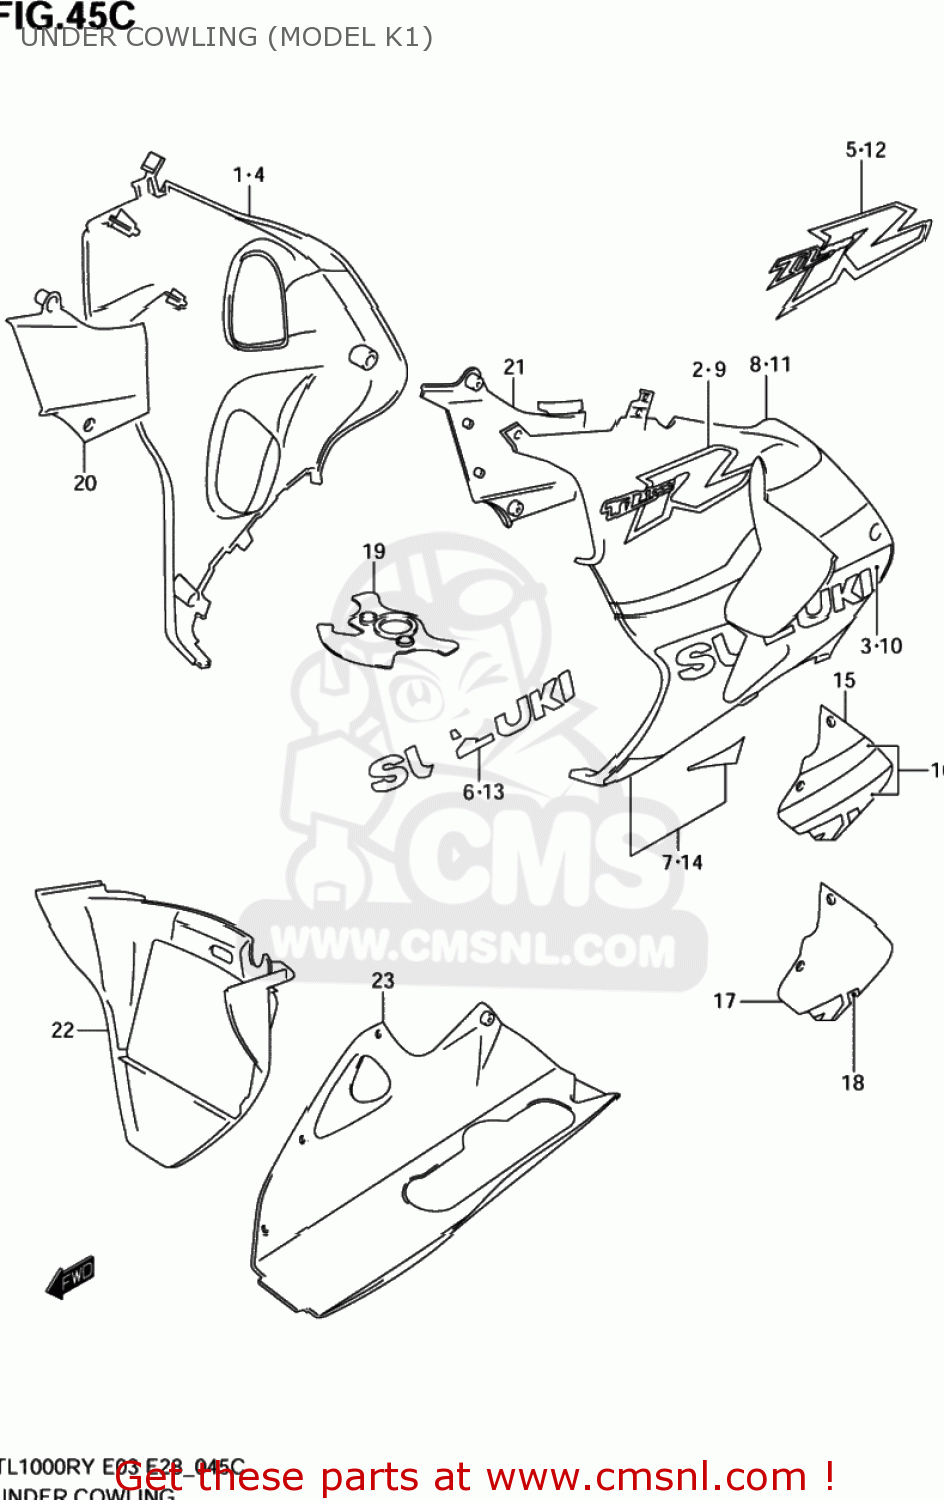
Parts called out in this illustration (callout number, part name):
1	COWLING ASSY,UNDER,R
2	EMBLEM,TL1000R,R
3	TAPE SET,UNDER,R
4	COWLING ASSY,UNDER,R
5	EMBLEM,TL1000R,R
6	EMBLEM,SUZUKI,R(BLACK)
7	TAPE SET,COWL UNDER,R(BLACK)
8	COWLING ASSY,UNDER,L
9	EMBLEM,TL1000R,L
10	TAPESET ONDER
11	COWLING ASSY,UNDER,L
12	EMBLEM,TL1000R,L
13	EMBLEM,SUZUKI,L(BLACK)
14	TAPE SET,COWL UNDER,L(BLACK)
15	LID ASSY,COWL UNDER,L
16	TAPE,LID,L
17	LID ASSY,COWL UNDER,L
18	EMBLEM,LIP,L(BLACK)
19	COVER,LWR BRACKET
20	COWLING,UNDER INNER,R
21	COWLING,UNDER INNER,L
22	COWLING,UNDER CTR
23	COWLING,UNDER RR
